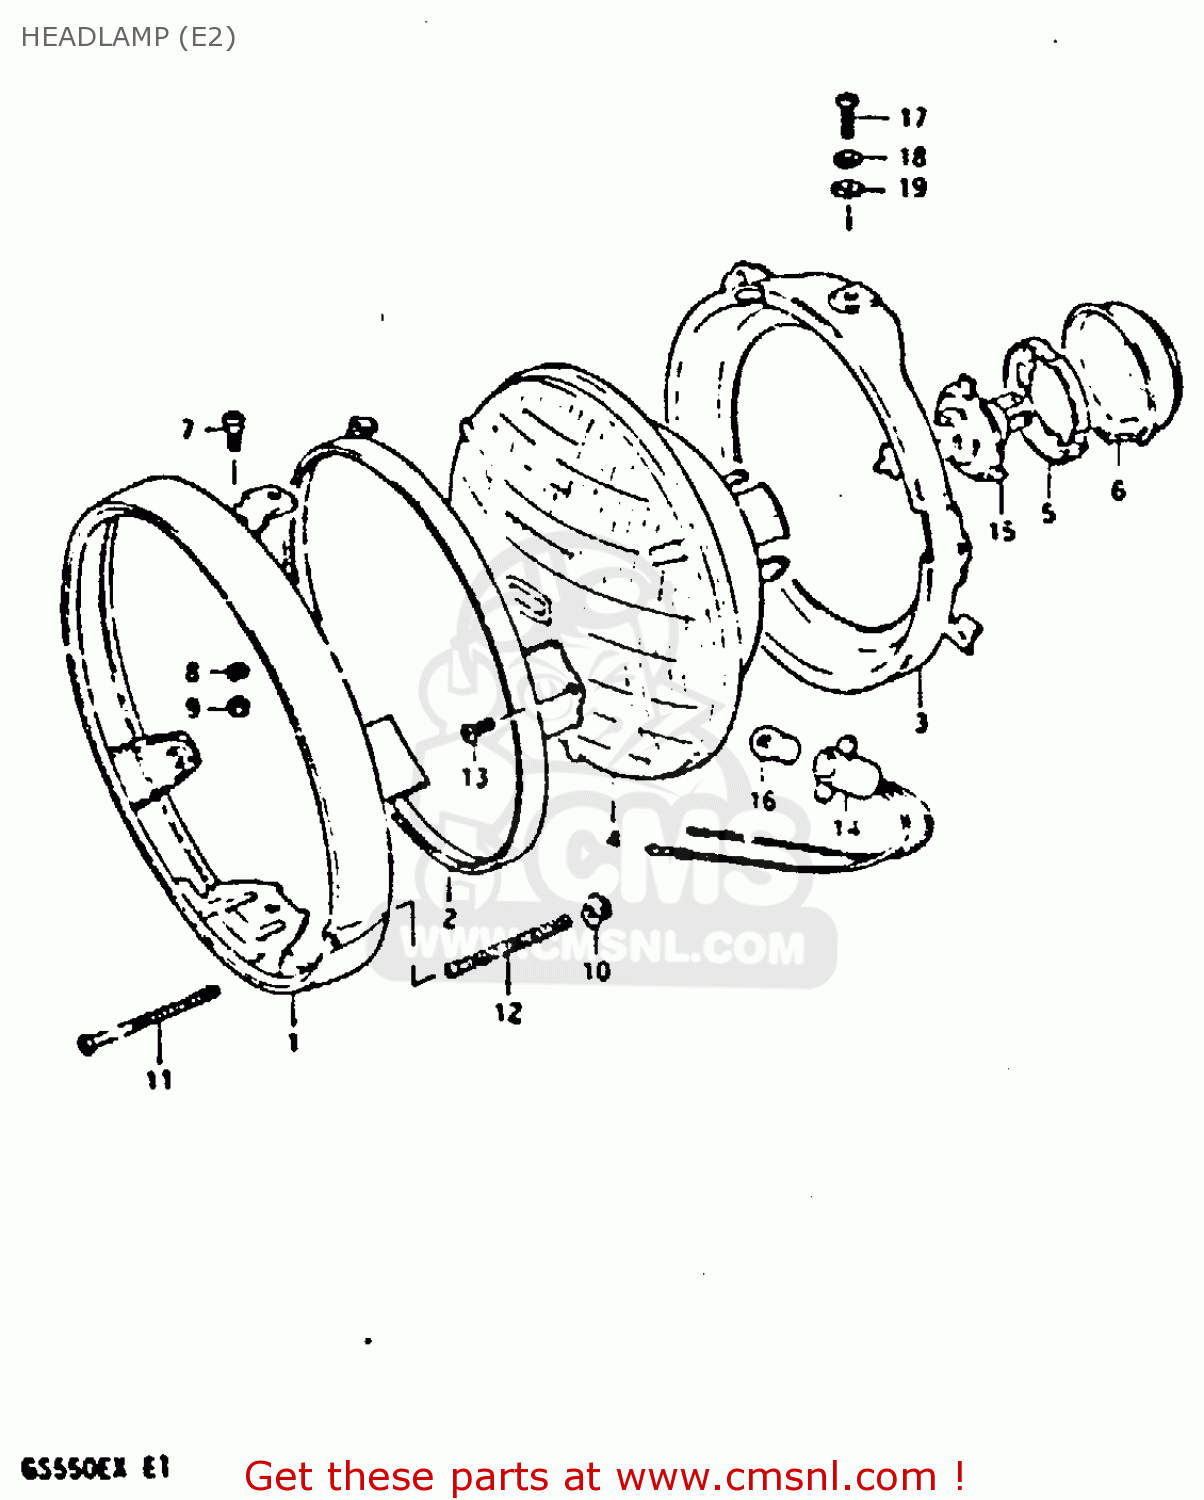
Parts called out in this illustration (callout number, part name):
1	RIM
2	RETAINING RING
3	RING
4	UNIT
5	SETTING,BULB
6	COVER,HEADLAMP SOCKET
7	H/LAMP LENS UNIT FITING SCRE
8	LOCK WASHER
9	NUT
10	NUT
11	SCREW,HEADLAMP ADJUST
12	SPRING,ADJUSTING
13	SCREW
14	SOCKET
15	BULB(12V60/55W,H4)
16	BULB
17	SCREW
18	WASHER,LOCK
19	WASHER
